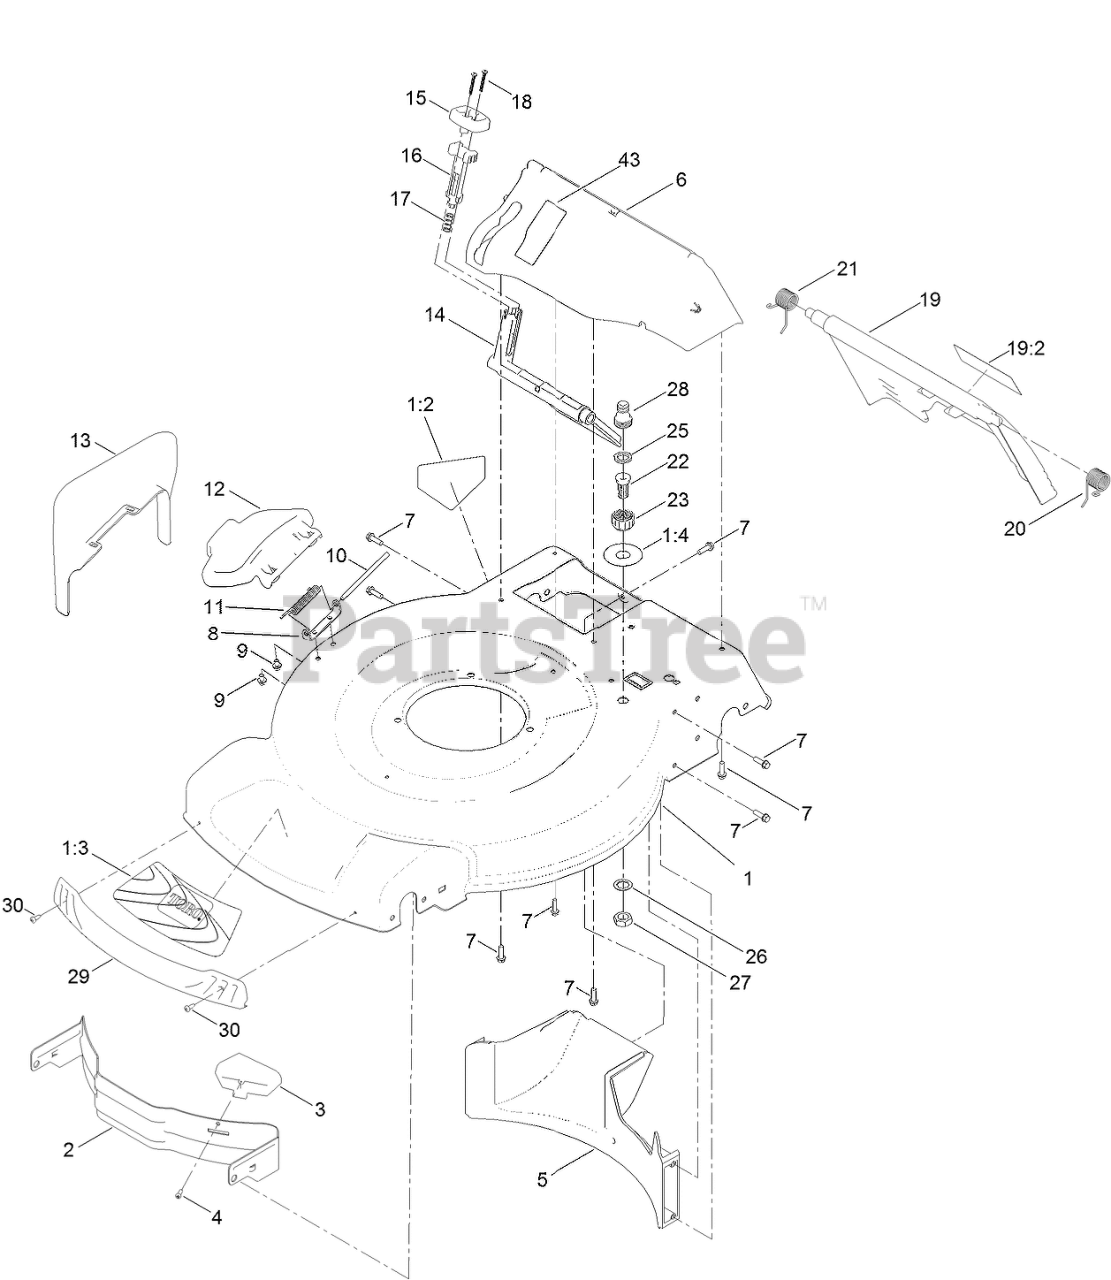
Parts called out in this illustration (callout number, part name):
1	HOUSING ASM
1:2	DECAL-DANGER
1:4	DECAL-PORT, WASHOUT
2	BAFFLE-FRONT
3	KICKER-FRONT
4	SCREW-PPH
5	BAFFLE-REAR
6	CHUTE-RECYCLE
7	SCREW-HWH
8	BRACKET-COVER
9	SCREW-HWH
10	ROD-COVER
11	SPRING-TORSION
12	DEFLECTOR-SIDE
13	CHUTE-DISCHARGE, SIDE
14	DEFLECTOR-RECYCLE
15	KNOB-RECYCLE
16	LATCH-RECYCLE
17	SPRING-COMPRESSION
18	SCREW-PPH
19	REAR DOOR ASM
19:2	DECAL-WARNING
20	SPRING-TORSION
21	SPRING-TORSION
22	PORT-WASHOUT
23	COUPLING-HOSE, WASHOUT PORT
25	WASHER-SEAL, WASHOUT PORT
26	WASHER-TOOTH, INTERNAL
27	NUT-JAM
28	ADAPTER-CONNECT, QUICK
29	BUMPER
30	SCREW-FORMING, THREAD
